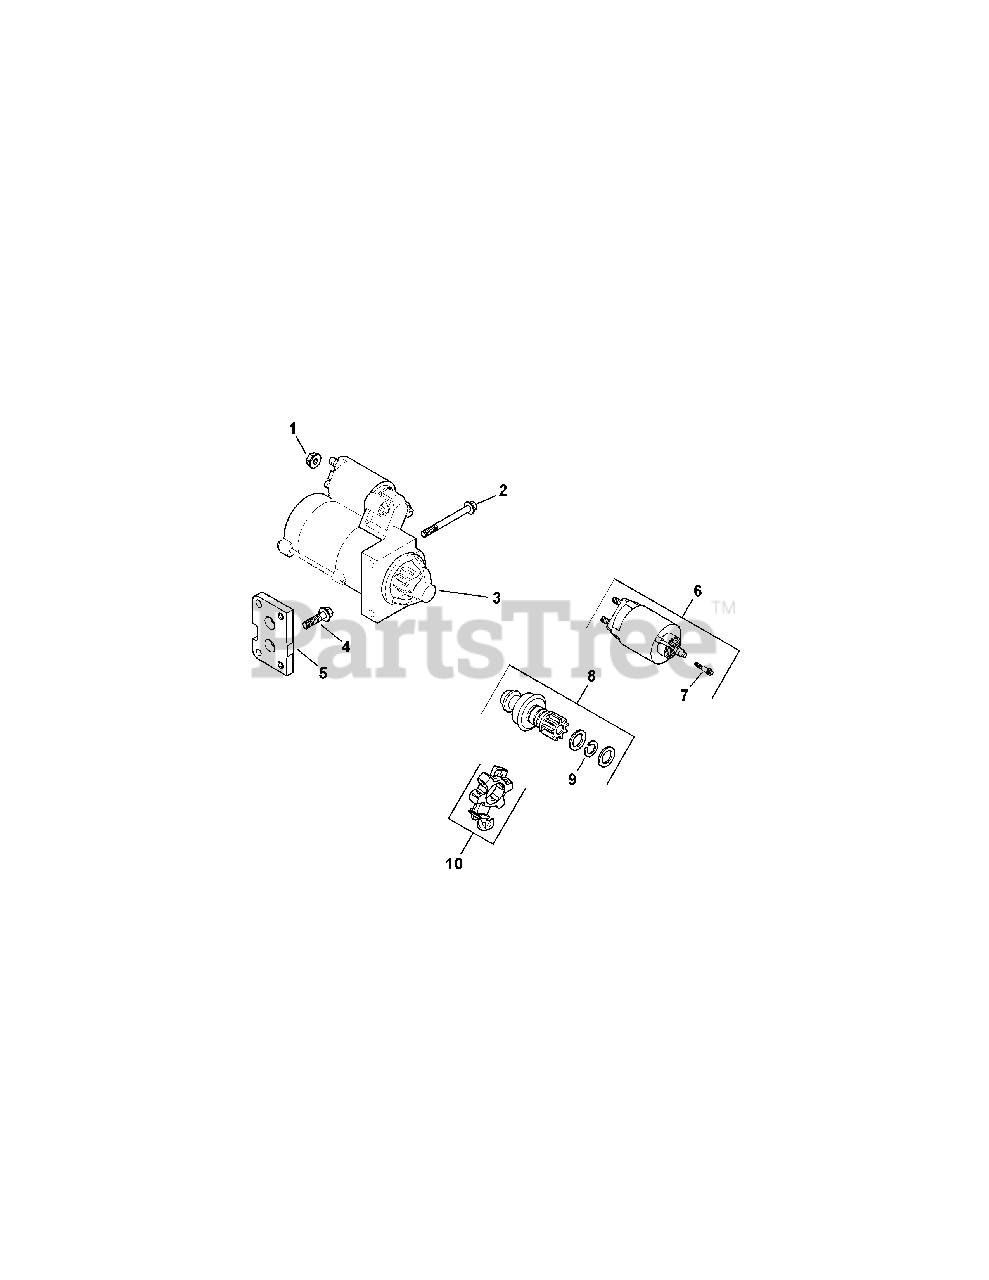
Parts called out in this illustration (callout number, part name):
1	Nut, Flg, M8 x 1.25
2	Screw, Flg, M8 x 1.25 x 80
3	Starter Ass’y, Solenoid Shift
4	Screw, Flg, M8 x 1.25 x 30
5	Plate, Starter
6	Kit, Solenoid (Includes 7)
7	Screw, External Torx Head
8	Kit, Starter Pinion (Includes 9)
10	Brush, Holder
